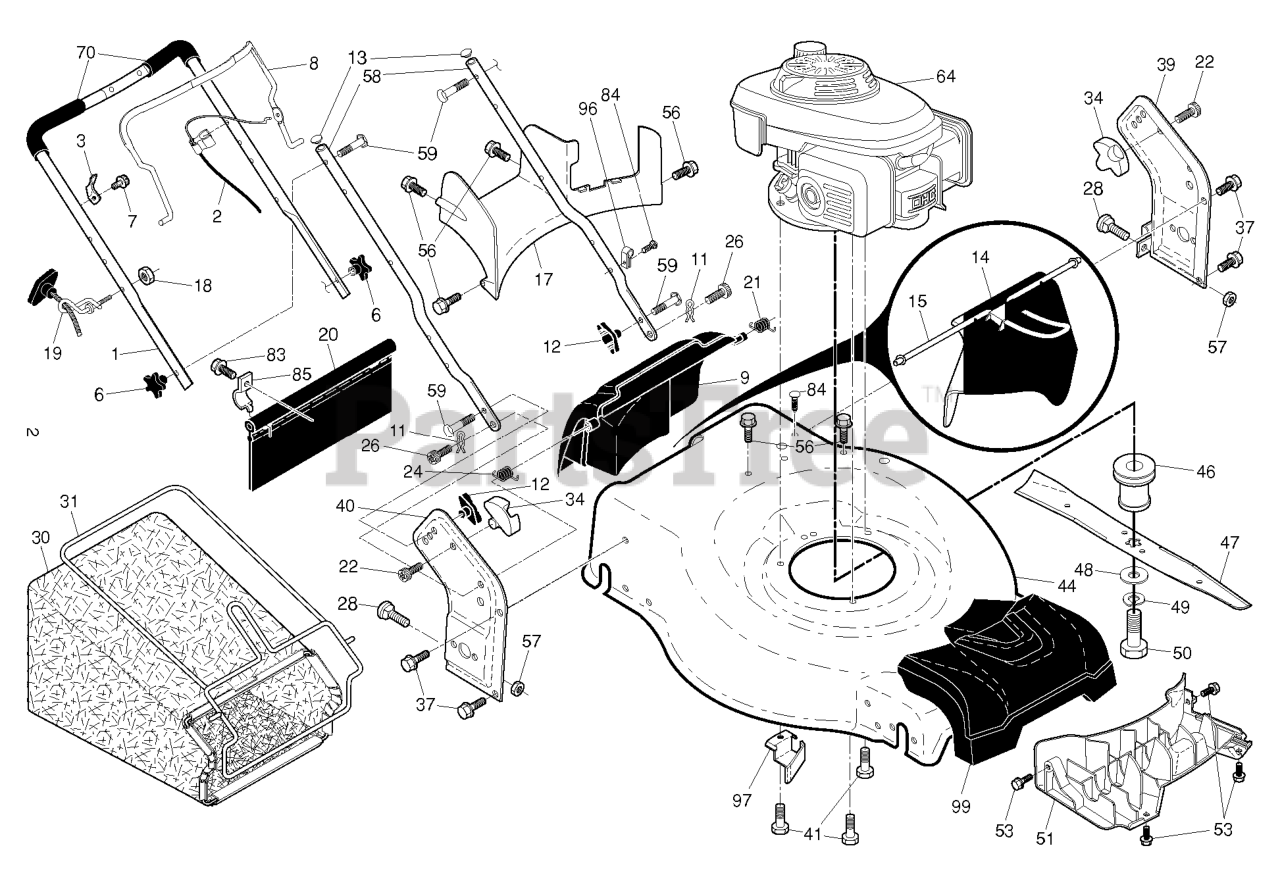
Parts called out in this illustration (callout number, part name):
1	HANDLE.ASM.UP.BS.AW2.GRIP.498
2	CABLE.MZR.50.SNAP-IN
3	BRACKET.UPSTOP.RT
6	KNOB.HANDLE.PLASTIC.STAR.BLACK
8	BAIL.CONTROL.MZR.BS.ORANGE
9	DOOR.REAR.ASM.22+.HUSQ.FG/RGD
11	COTTER.HAIRPIN.DOOR/HANDLE.PIV
12	KNOB, DEFLECTOR
13	PLUG.PLASTIC.7/8".14-20.GAUGE
14	DEFLECTOR.CHUTE.22+REAR
15	HANDLE DEFLECTOR.22+REAR
17	BAFFLE.REAR.22+RGD.AWD.PLASTIC
18	NUT
19	RB GUIDE.ROPE.STD.BLK.ZIN WSL
20	SKIRT.REAR.22+RGD.HIGH WHEEL
21	SPRING.LH.BLACK
22	SCREW.PAN.HEAD.#10
24	SPRING.RH.GRAY
26	SCREW,DOOR/HANDLE.PIVOT
28	BOLT
30	GBAG.A3610247T.SILV.HUSWT.BLUE
31	RB FRAME.GBAG.22PLUS
34	BRACKET.GRASSBAG.ATTACHING.BLK
37	BOLT.5/16HEX.WHS.HD
39	BRACKET.ASM.HNDL.LT.22+.GREY
40	BRACKET.ASM.HNDL.RT.22+.GREY
41	BOLT 3/8-16X1-1/8
44	HOUSING.22+.RWD.HD.WO/PORT.ORN
46	ADAPTER.BLADE.25MM.3MPH
47	BLADE.22+.PREMIUM/PREC.FGD/RGD
48	WASHER,HARDEN
49	LOCKWASHER
50	SCREW, HEX HD 3/8-24 X 1-3/8
51	BAFFLE.FRONT.22+PLASTIC.(2 2)
53	SCREW.HI-LO.5/16 X.75
56	SCREW.HX.13X.750
57	NUT.FLANGE.5/16
58	HANDLE.LOWER.22+BT.2PC.GRY
59	BOLT, HANDLE 5/16-18X1.75
70	GRIP.HANDLE.FOAM.WIDE.(1 SIDE)
83	TAPPING SCREW
84	FASTENER.PUSH.O.250X0.783
85	BRACKET.SKIRT.22+.BZP
96	CLIP.CABLE.BLK
97	BRACKET.BELT.GUIDE.22+.BZP
99	COVER.ASM.FRONT.SHROUD.HUSQ.
